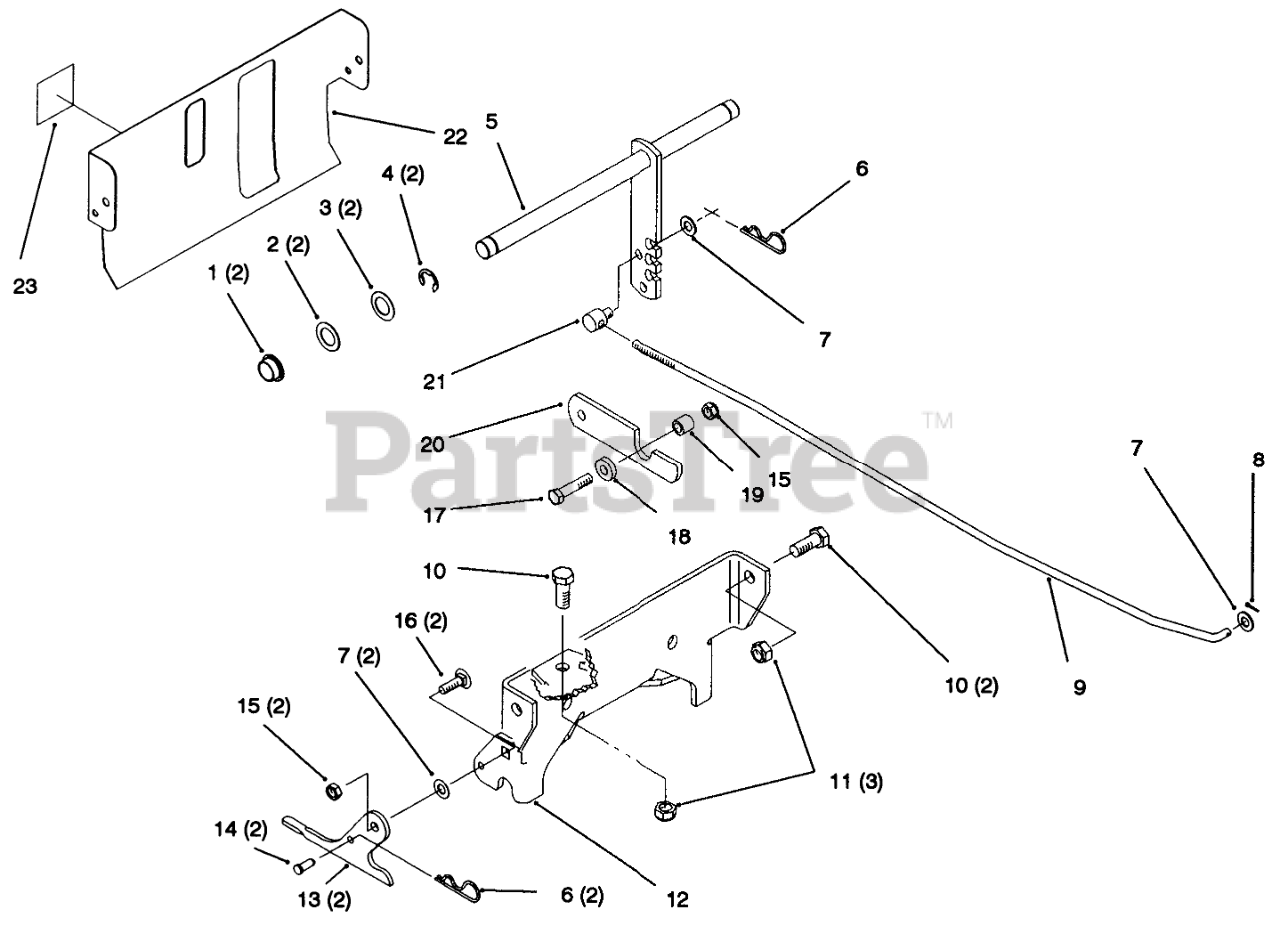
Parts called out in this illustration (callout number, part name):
1	BUSHING-BRONZE
2	WASHER
3	WASHER-SHIM
4	E-RING
5	LEVER ASM
6	PIN-HAIR
7	WASHER-FLAT
8	PIN-COTTER
9	ROD-LIFT
10	SCREW-HH
11	NUT-LOCK, NI
12	BRACKET-MOUNTING
13	PLATE-LATCHING
14	PIN-CLEVIS
15	NUT-LOCK, NI
16	BOLT-CARR
17	SCREW-HH
18	Washer
19	SPACER
20	CATCH-SPRING
21	TRUNNION-CLUTCH ROD
22	Cover-Rear
23	DECAL-LEVEL, FUEL
